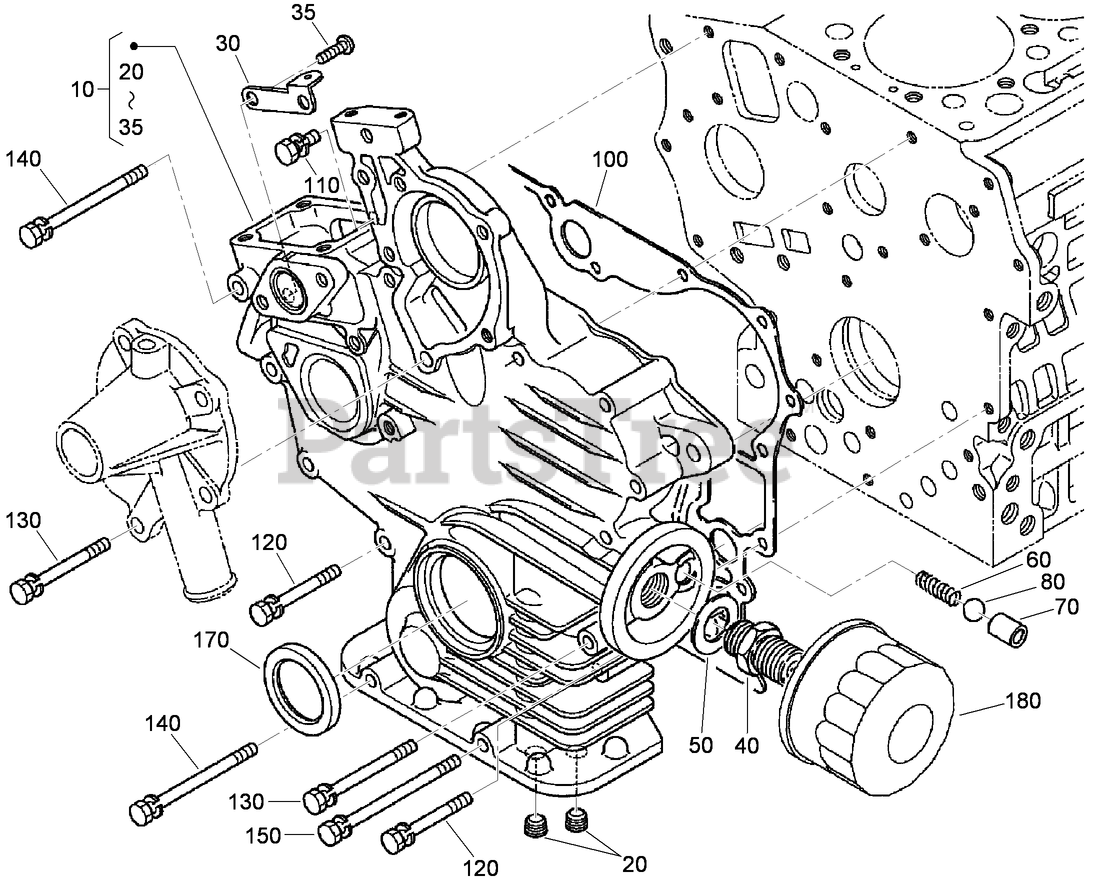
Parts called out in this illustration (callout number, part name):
10	GEAR CASE ASM
30	STAY-SPRING, START
40	JOINT-PIPE
50	WASHER-PLAIN
60	SPRING
70	SEAT-VALVE
100	GASKET-CASE, GEAR
170	SEAL-OIL
180	CARTRIDGE-FILTER, OIL
